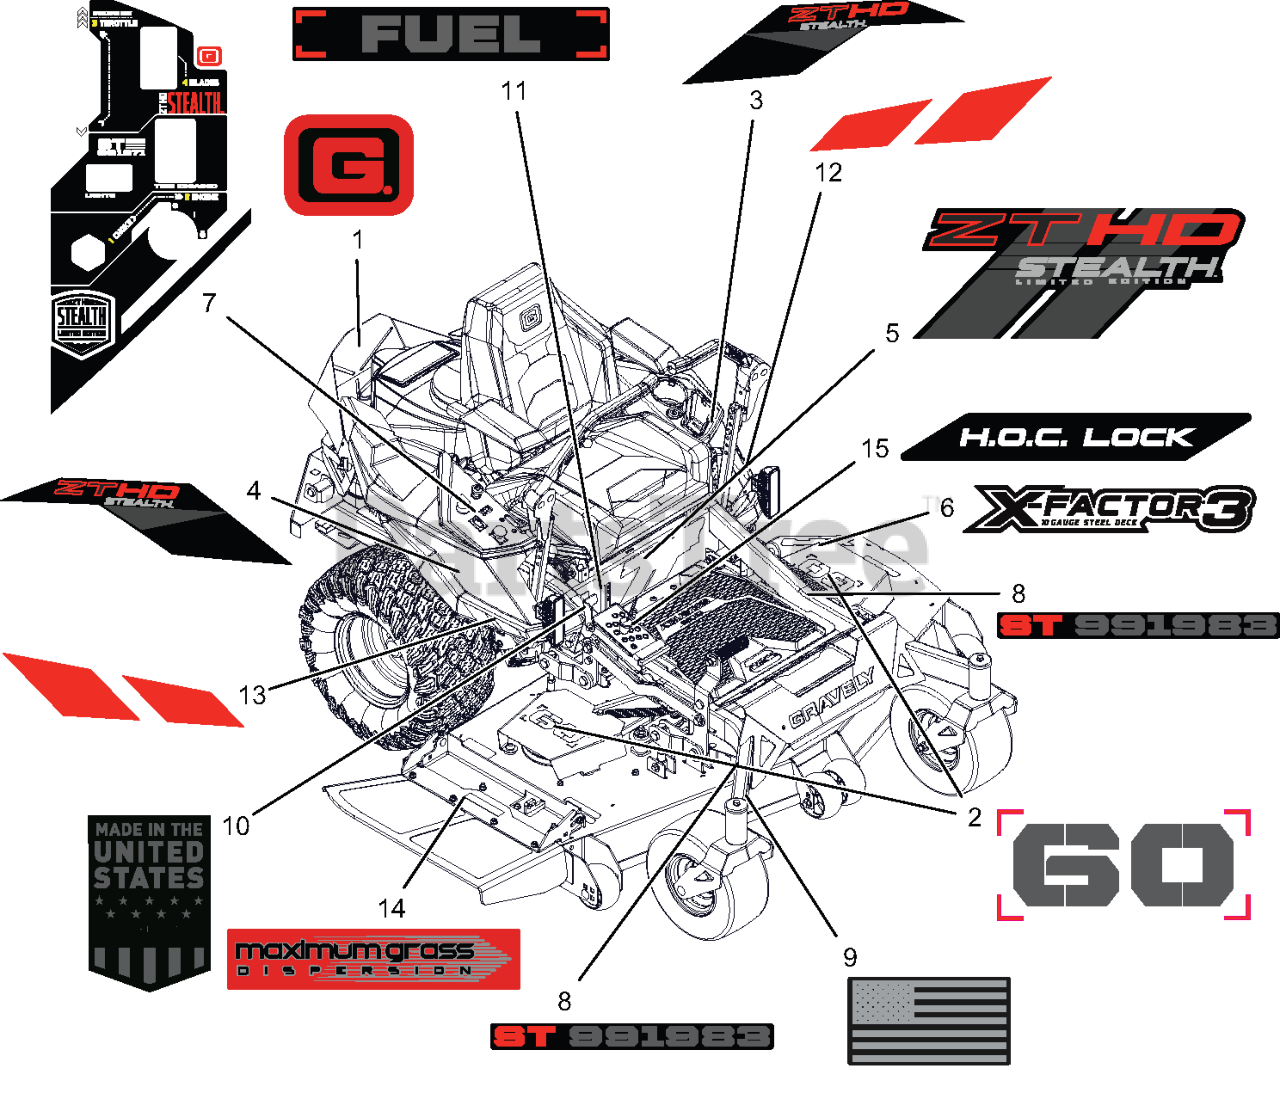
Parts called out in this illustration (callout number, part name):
1	DECAL- GRAVLEY
2	DECAL- HD STEALTH 60 DECK
3	DECAL- HD STEALTH FENDER L
4	DECAL- HD STEALTH FENDER R
5	DECAL- HD STEALTH KICKPLATE
6	DECAL, STEALTH X-FACTOR3 7GA
7	DECAL- CONTROLS HD STEALTH
8	DECAL- HD STEALTH ST 991983
9	DECAL- HD STEALTH USA FLAG
10	DECAL- HD STEALTH MADE IN USA
11	DECAL- HD STEALTH FUEL
12	DECAL- HD STEALTH STRIPES L
13	DECAL- HD STEALTH STRIPES R
14	DECAL, DECK - MAX GRASS
15	DECAL- HD STEALTH HOC LOCK
